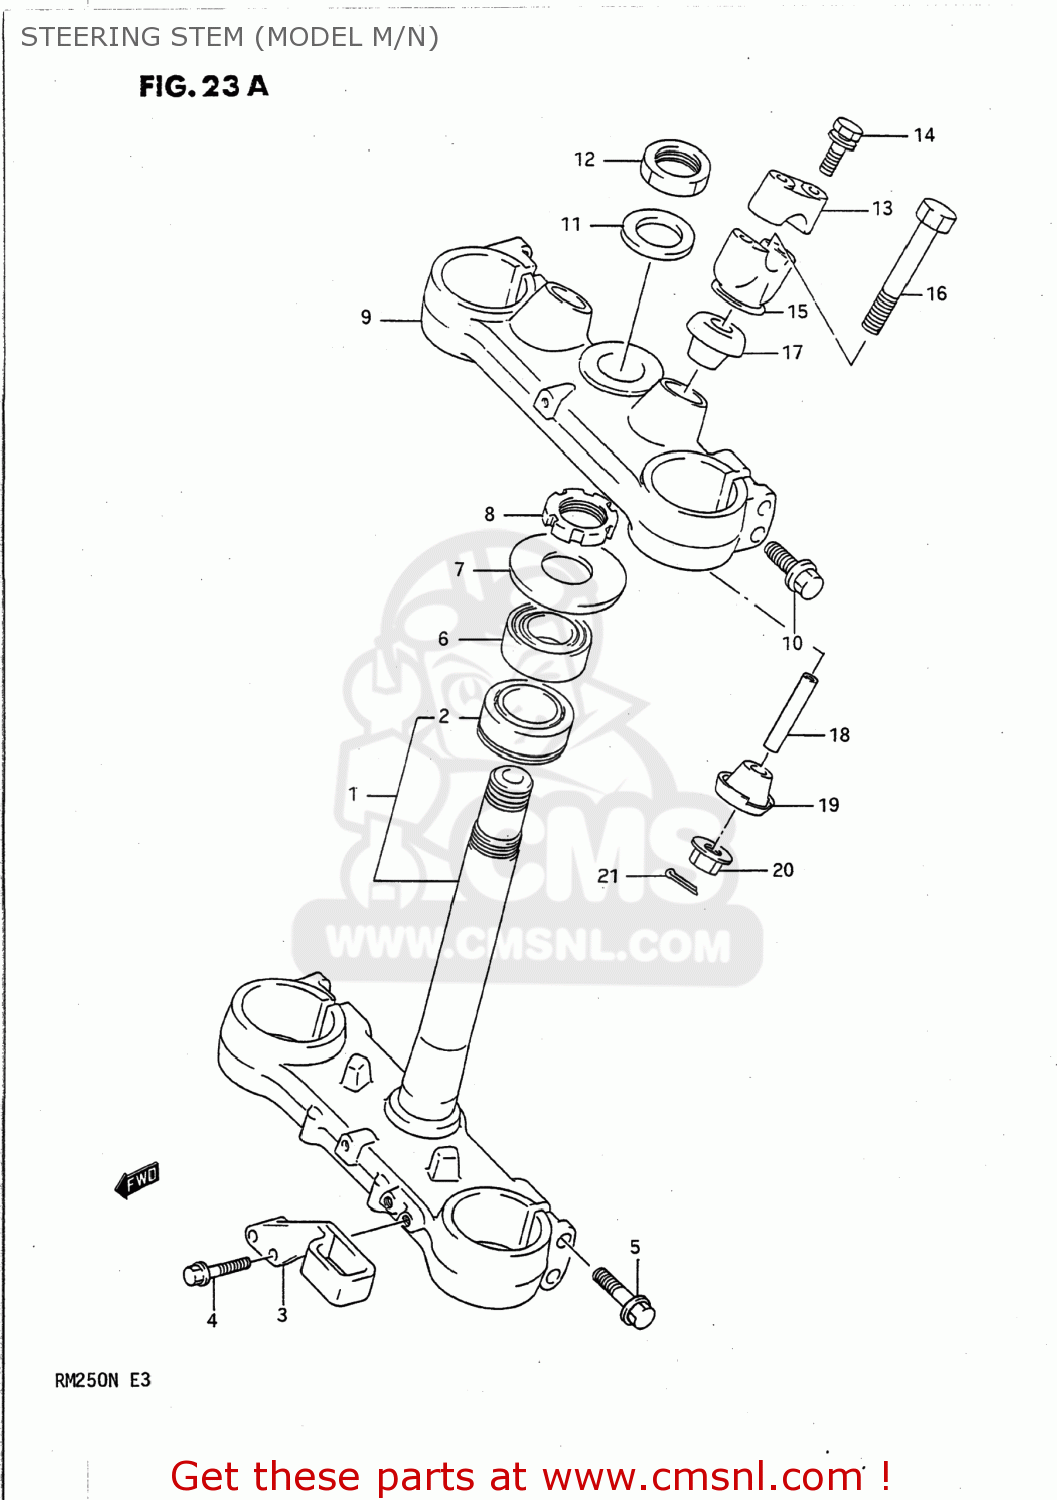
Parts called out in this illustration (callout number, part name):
1	STEM,STEERING
2	BEARING(30X52X16)
3	GUIDE,HOSE
4	BOLT,GUIDE
5	BOLT,STEM 8X45
6	BEARING
7	SEAL,STEERING,UPPER DUST
8	NUT,STEERING
9	HEAD,STEERING STEM
10	BOLT,STEM 8X45
11	WASHER,STEM HEAD
12	NUT,STEM HEAD
13	HOLDER,HANDLEBAR
14	BOLT,HANDLE HOLDER(8X35)
15	HOLDER,HANDLE UNDER
16	BOLT,LWR HOLDER
17	CUSHION,RUBBER UPR
18	SPACER
19	CUSHION,RUBBER UNDER
20	NUT
21	COTTER PIN
